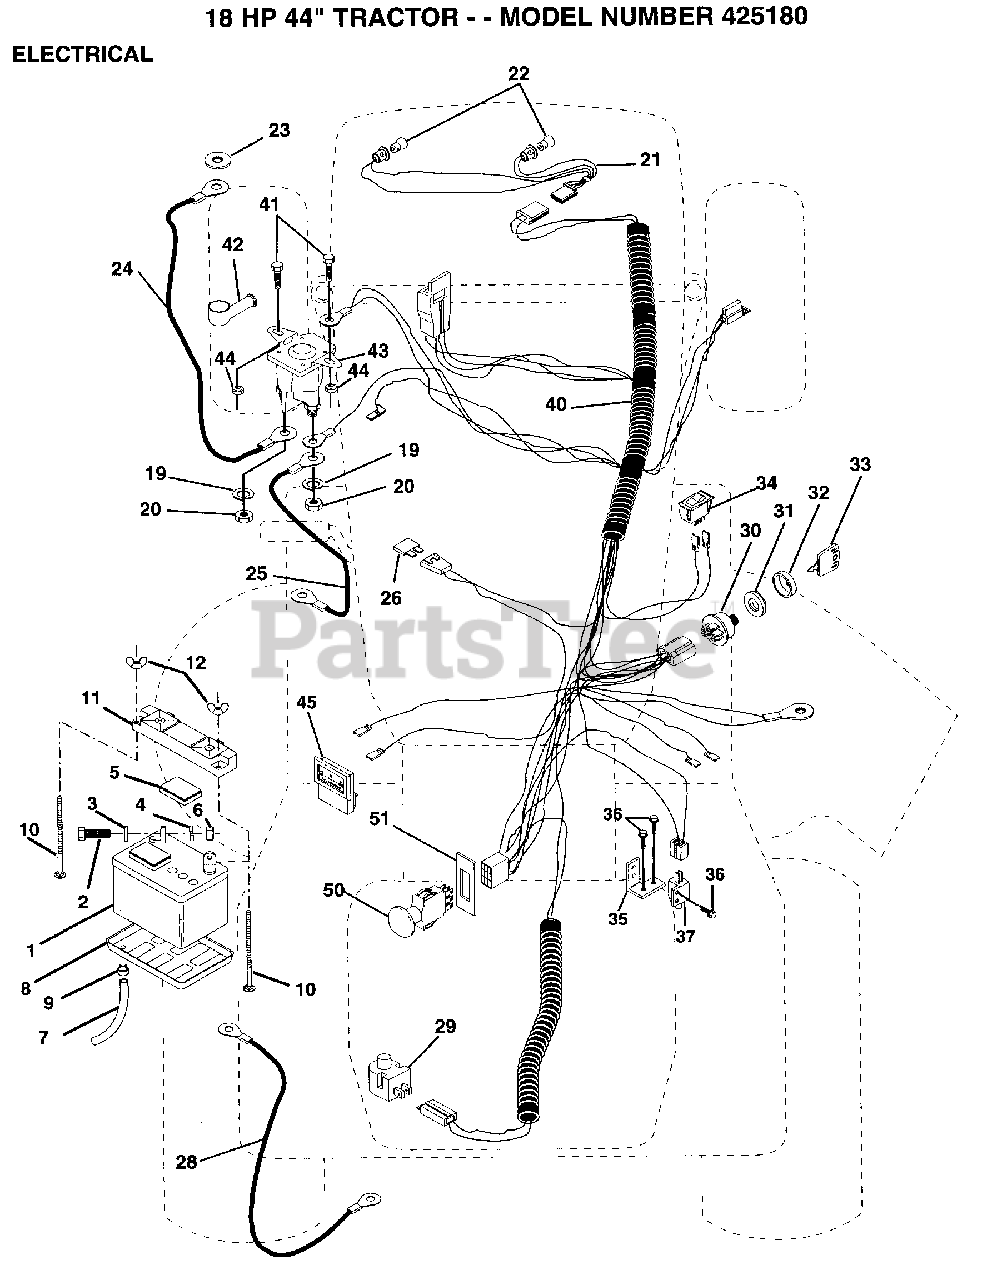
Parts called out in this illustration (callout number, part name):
2	BOLT LT
3	WASHER
4	LOCKWASHER
5	"CAP,BATTERY "
7	"DRAIN TU T, BATT"
8	"TRAY T, BATTERY"
9	HOSE CLAMP T
10	BOLT
20	NUT
21	"HARNESS,LIGHT SOC"
22	HEADLAMP BULB
23	LOCKWASHER
24	"CABLE T, BATTERY"
25	CABLE ASM.
26	FUSE HYT
28	CABLE T
29	SWITCH SEAT
31	NUT IGNITION
33	KEY
34	SWITCH LT
35	BRACKET LT
36	SCREW
37	SWITCH-INTER. GT
38	SWITCH BRACKET
40	HARNESS IGNITION
41	BOLT
44	NUT
45	AMMETER
51	RING RETAIN PTO
70	HARNESS.ENG.KOHL
